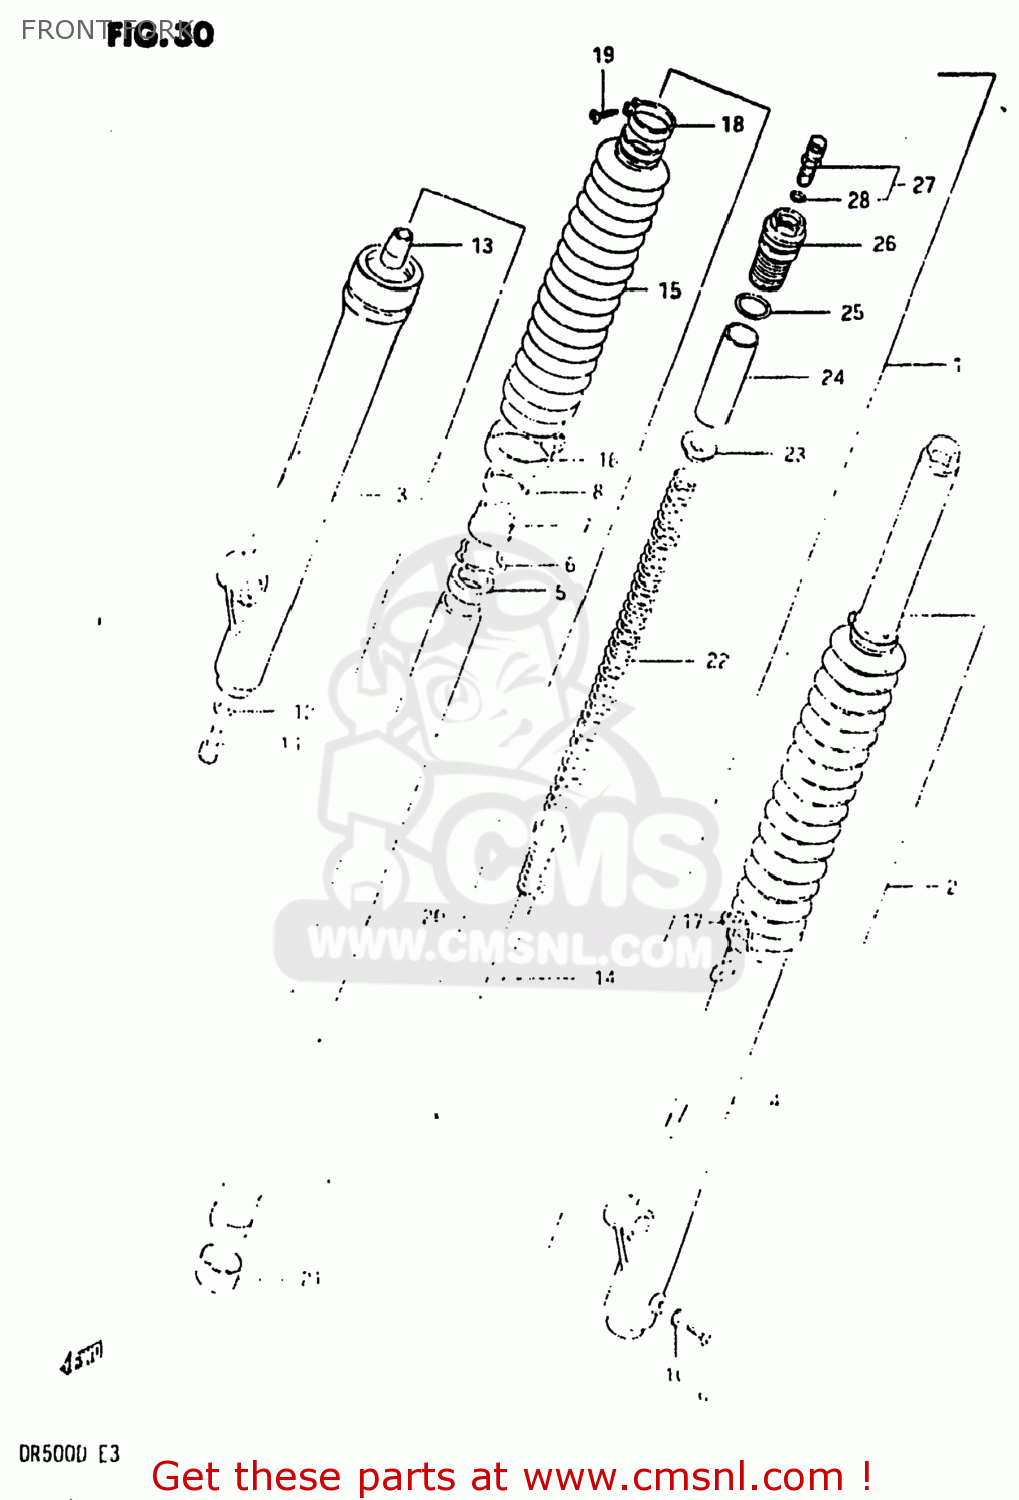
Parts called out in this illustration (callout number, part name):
1	DAMPER ASSEMBLY,RIGHT
2	DAMPER ASSEMBLY,LEFT
3	TUBE,OUTER,RIGHT
4	TUBE,OUTER,LEFT
5	OIL SEAL,FRONT FORK
6	7
7	SEAL,DUST
8	SCREW
9	GASKET,DRAIN,PLUG (NAS)
10	BOLT,FORK CYLINDER(10X25)
11	BOLT,FORK CYLINDER(10X25)
12	GASKET (NAS)
13	PIECE,OIL LOCK
14	CYLINDER,FRONT FORK
15	BOOT
16	BAND,FRONT FORK COVER
17	BAND,FRONT FORK COVER
18	BAND,BOOT
19	SCREW
20	TUBE,FORK,INNER
21	PISTON
22	SPRING,FRONT FORK
23	GUIDE,FRONT FORK SPRING C
24	COLLAR,SPRING
25	O RING
26	BOLT,FORK
27	VALVE,FRONT FORK AIR
28	O-RING
